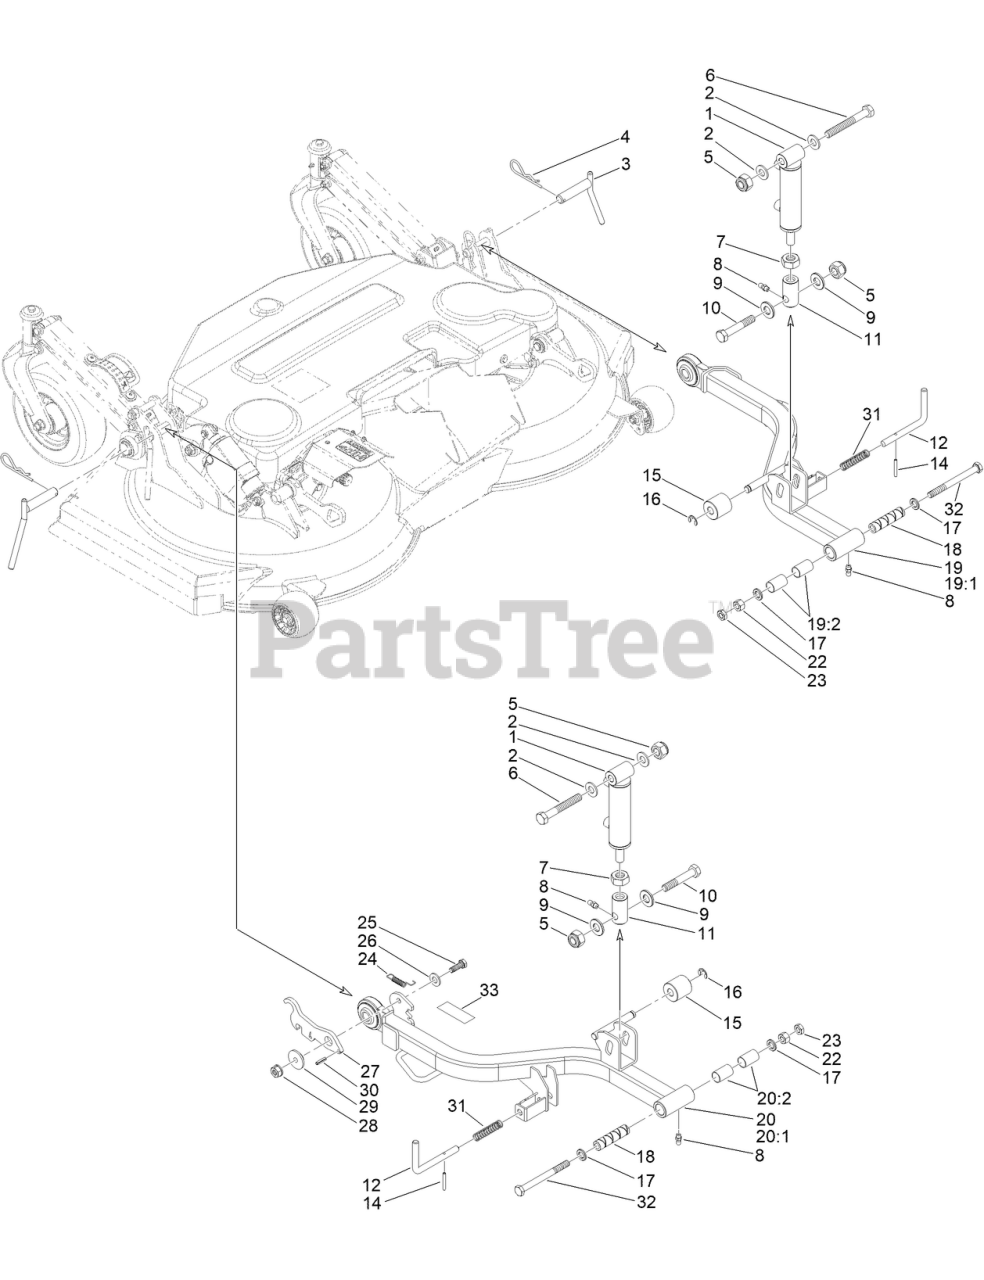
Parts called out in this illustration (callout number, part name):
2	WASHER
3	PIN-PIVOT
4	PIN-SPRING
6	SCREW, HH CAP
8	FITTING-GREASE
9	WASHER-PLASTIC
10	SCREW, HH CAP
11	SUPPORT
12	PIN-UNHOOKING
14	PLUG-SPIROL
15	ROLLER, PLATFORM
16	RING-SNAP
17	WASHER-PLAIN, CHAMFERED
18	BUSHING
19	RH ARM ASSY, DECK
19:1	RH ARM, DECK
19:2	BUSHING
20	LH ARM ASSY, DECK
20:1	LH ARM, DECK
20:2	BUSHING
22	NUT-HEX
24	SPRING
26	WASHER
27	HOOK, DECK
29	BUSHING
30	PLUG-SPIROL
31	SPRING
32	SCREW-HH
33	TAPE, NON-SLIP
